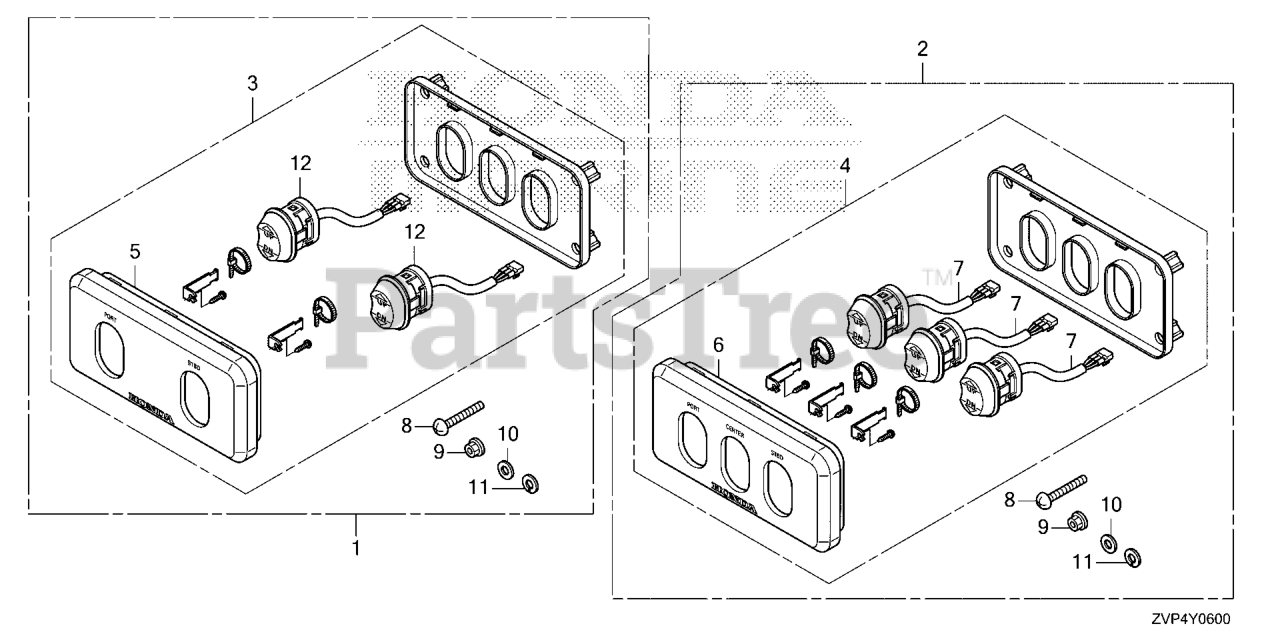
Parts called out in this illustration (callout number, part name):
1	PANEL KIT, POWER TRIM-TILT SWITCH (TWIN)
2	PANEL KIT, PTT SW
3	PANEL ASSY., POWER TRIM-TILT SWITCH (TWIN)
4	PANEL ASSY., POWER TRIM-TILT SWITCH (TRIPLE)
5	PANEL, POWER TRIM-TILT SWITCH (TWIN)
6	PANEL, POWER TRIM-TILT SWITCH (TRIPLE)
7	SWITCH ASSY., POWER TILT
8	SCREW, PAN (5X40) DUAL QTY = (8) (SINGLE)
9	NUT, FLANGE (5MM)
10	WASHER, PLAIN (5MM)
11	WASHER, SPG (5MM)
12	SWITCH ASSY., POWER TILT
